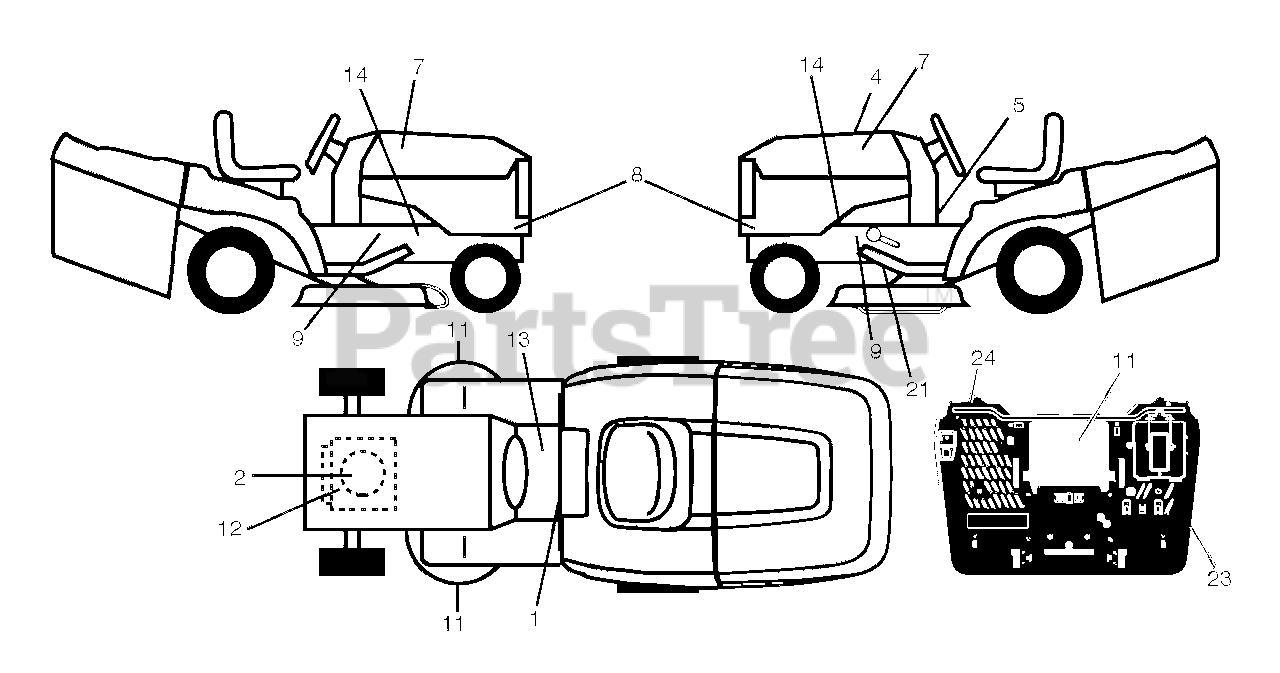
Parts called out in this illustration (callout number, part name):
1	DECAL.TRAC.FNDR.GLBLWRNG.RDYST
2	DECAL.ENGINE.WARNING
4	Decal, Replacement BSM40 ENDUR TCRD 97E
5	Decal, Instruction MLCH/BG VERT
7	DECAL.BADGE.170MM.TEXTLOGO.
8	Decal, Tractor Side Panel Husqvarna
9	DECAL.WARNING.SERVCE/FIRE
11	DECAL.CUTFINGER.CE.02
12	DECAL.ENG.BS.656.ENDUR.382292
13	DECAL.FWD/REV.PEDAL.SYMBOL
14	DECAL.CHASSIS.HOT.MUFFLER
21	DECAL DECAL V-BELT 97 CM CRD
23	DECAL DECAL.BYPASS.BACKPLATESI
24	DECAL DECAL.WARNING.COMBINED.T
